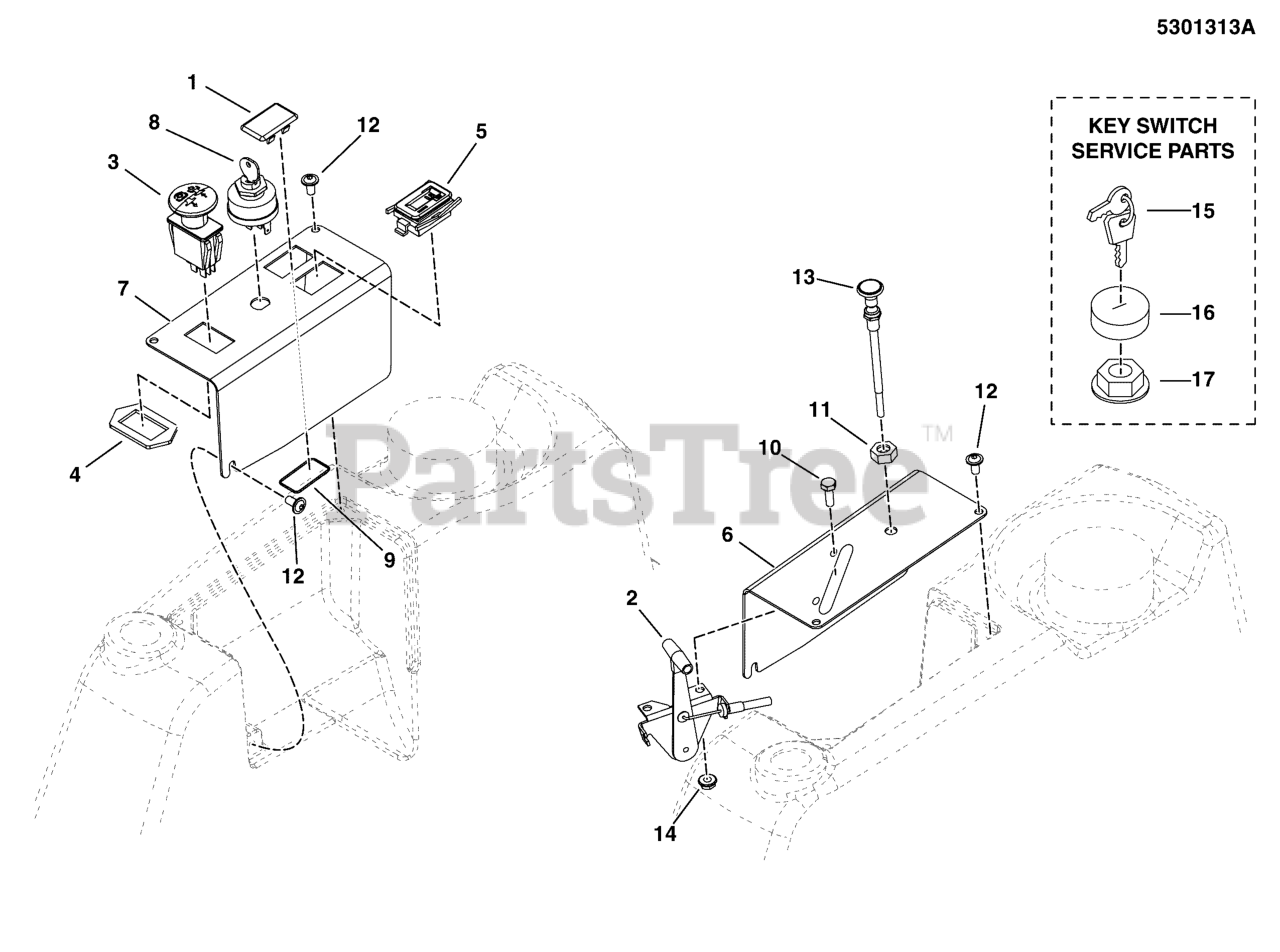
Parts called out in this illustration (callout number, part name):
1	PLUG, .820X1.44 HOLE, BLACK PLASTIC
2	CABLE, THROTTLE CONTROL, 51"
3	SWITCH-PTO PUSH
4	RING, SWITCH RETAINER
5	* HOUR METER, ASSEMBLY
6	CONTROL PANEL, LEFT - BLK
7	CONTROL PANEL, RIGHT - BLK
8	SWITCH, IGNITION, 6 POST
9	O-RING, 7/8 ID X 1/16 W
10	HHCS, 1/4-20 X 0.625, GR5, ZINC/CLEAR
11	NUT, 3/8-24 HEX JAM
12	SCREW, FLANGE, ALLEN HD, 1/4-20X.5 S/S
13	CABLE, CHOKE CONTROL, 51 (Z)
14	NUT, 1/4-20 HEX NYLOCK FLANGE
15	KEY, IGNITION MOLDED SET
16	COVER, PLASTIC, SNAP ON
17	PLASTIC NUT
